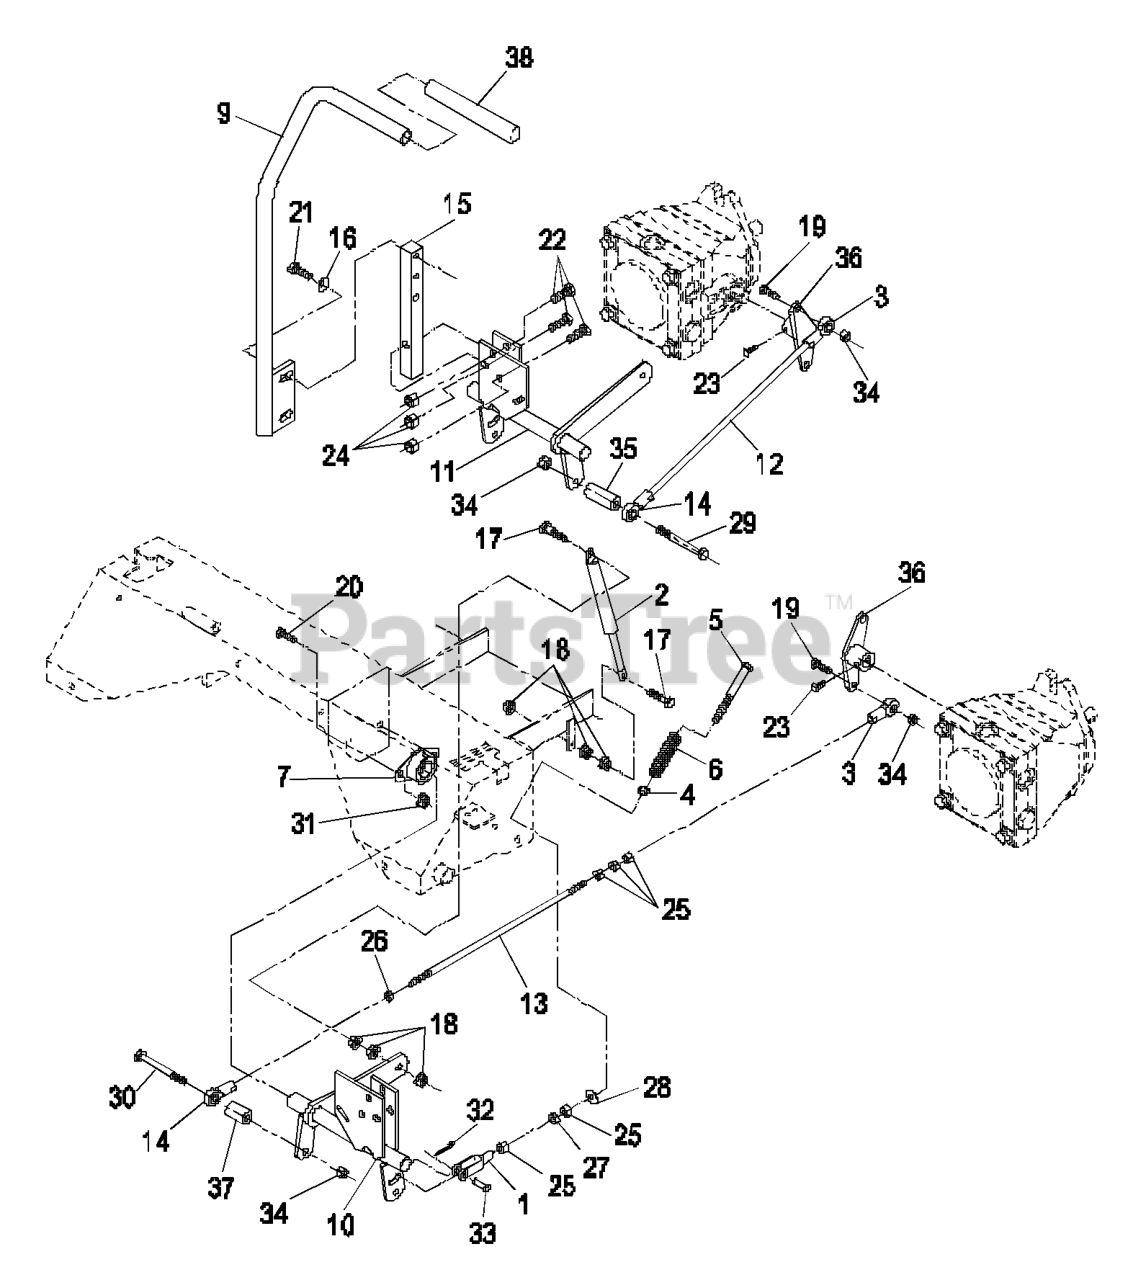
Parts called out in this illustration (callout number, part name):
1	YOKE-ADJUSTABLE
3	BALLJOINT-RH
4	BUSHING-FLANGED
5	BOLT-RETURN, NEUTRAL
6	SPRING-RETURN, NEUTRAL
7	BEARING-FLANGE, SIDE
9	RH LEVER ASM
14	BALLJOINT-LH
15	ARM-SHAFT, CONTROL
16	WASHER-BELLEVILLE
17	SCREW-HH
19	SCREW-HH
20	SCREW-HH
21	SCREW-HH
22	SCREW-HH
23	SCREW-SET
24	NUT-LOCK, NI
25	NUT-HEX
27	NUT-JAM
28	WASHER-FLAT
29	SCREW-HH
30	SCREW-HH
31	NUT-HHF, WHIZ
32	PIN-COTTER
33	PIN-CLEVIS
34	NUT-LOCK, NI
36	ARM-CONTROL, HYDRO
37	SPACER-HYDRO CONTROL, LH
38	GRIP-CONTROL, MOTION
